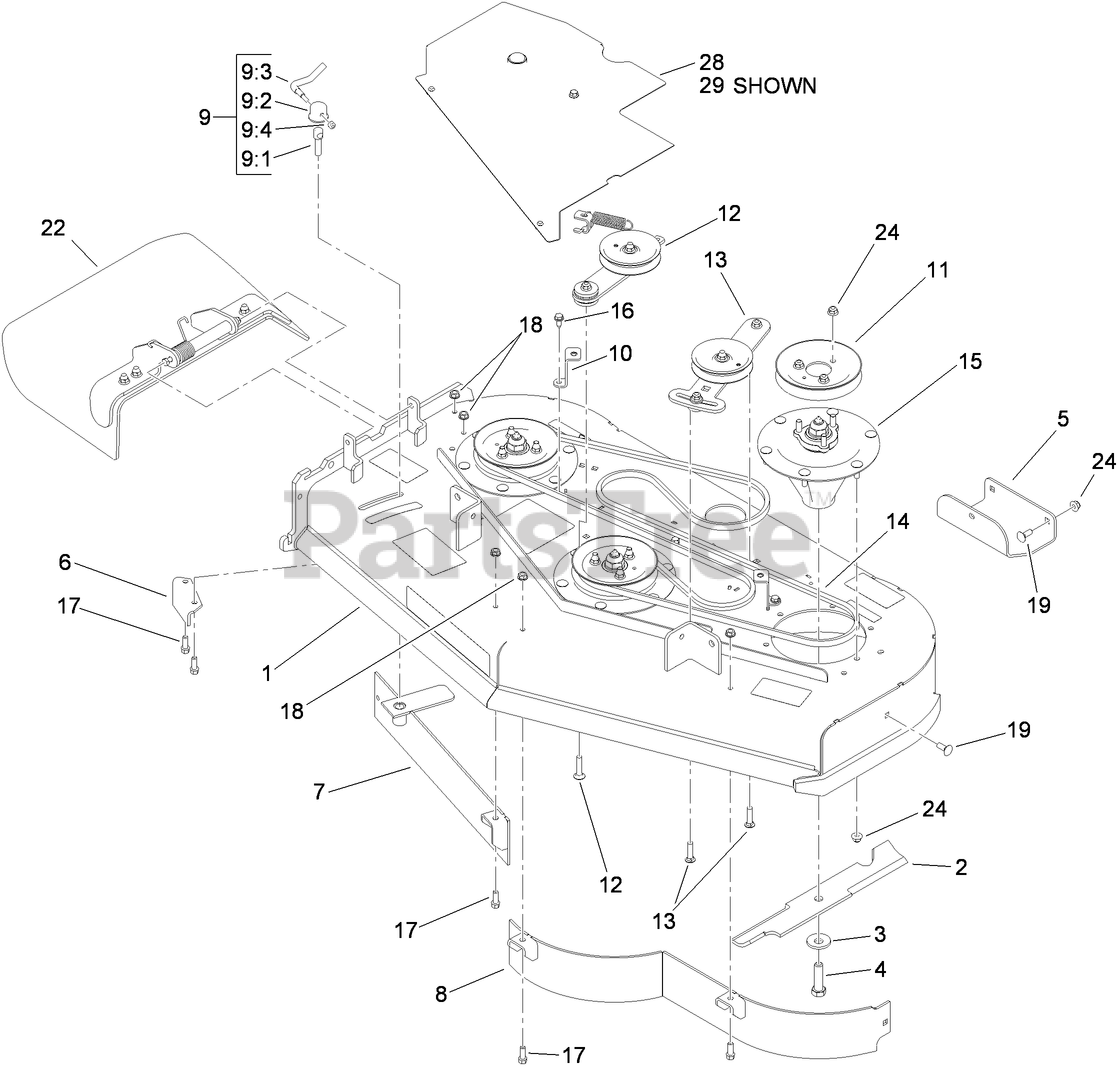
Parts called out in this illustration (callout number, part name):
1	DECK ASM
2	BLADE-16.5 INCH (HIGH FLOW)
3	Washer-Blade Bolt, Heavy
4	SCREW-BLADE
6	BAFFLE-DISCHARGE
7	BAFFLE ASM
8	48 INCH BAFFLE ASM
9	LEVER ASM
9:1	Screw-Lock
9:2	CAP-LOCK
9:3	Lever-Lock
9:4	NUT-LOCK, NI
10	BELT COVER BRACKET ASM
11	PULLEY
12	SPRING IDLER ASM
13	IDLER ADJUST ASM
14	BELT-V
15	SPINDLE ASM
16	SCREW-HWHTF
17	SCREW-HWH
18	NUT-HHF, WHIZ
19	BOLT-CARR
22	DEFLECTOR ASM
24	NUT-HF, NI
28	LH BELT COVER ASM
29	RH BELT COVER ASM
